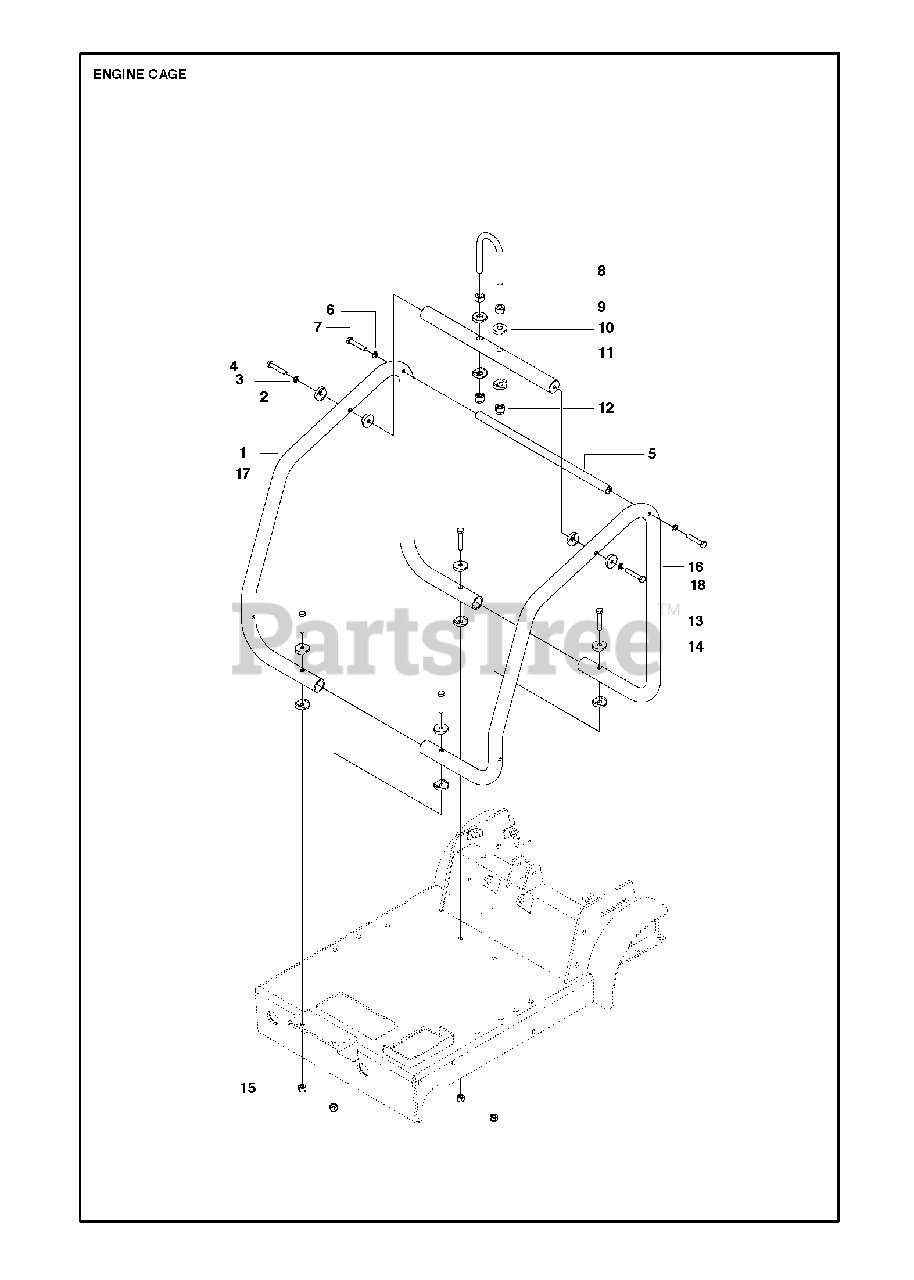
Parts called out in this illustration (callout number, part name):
3	SPRING WASHER
6	SPRING WASHER
15	HEXAGON LOCKING NUT
